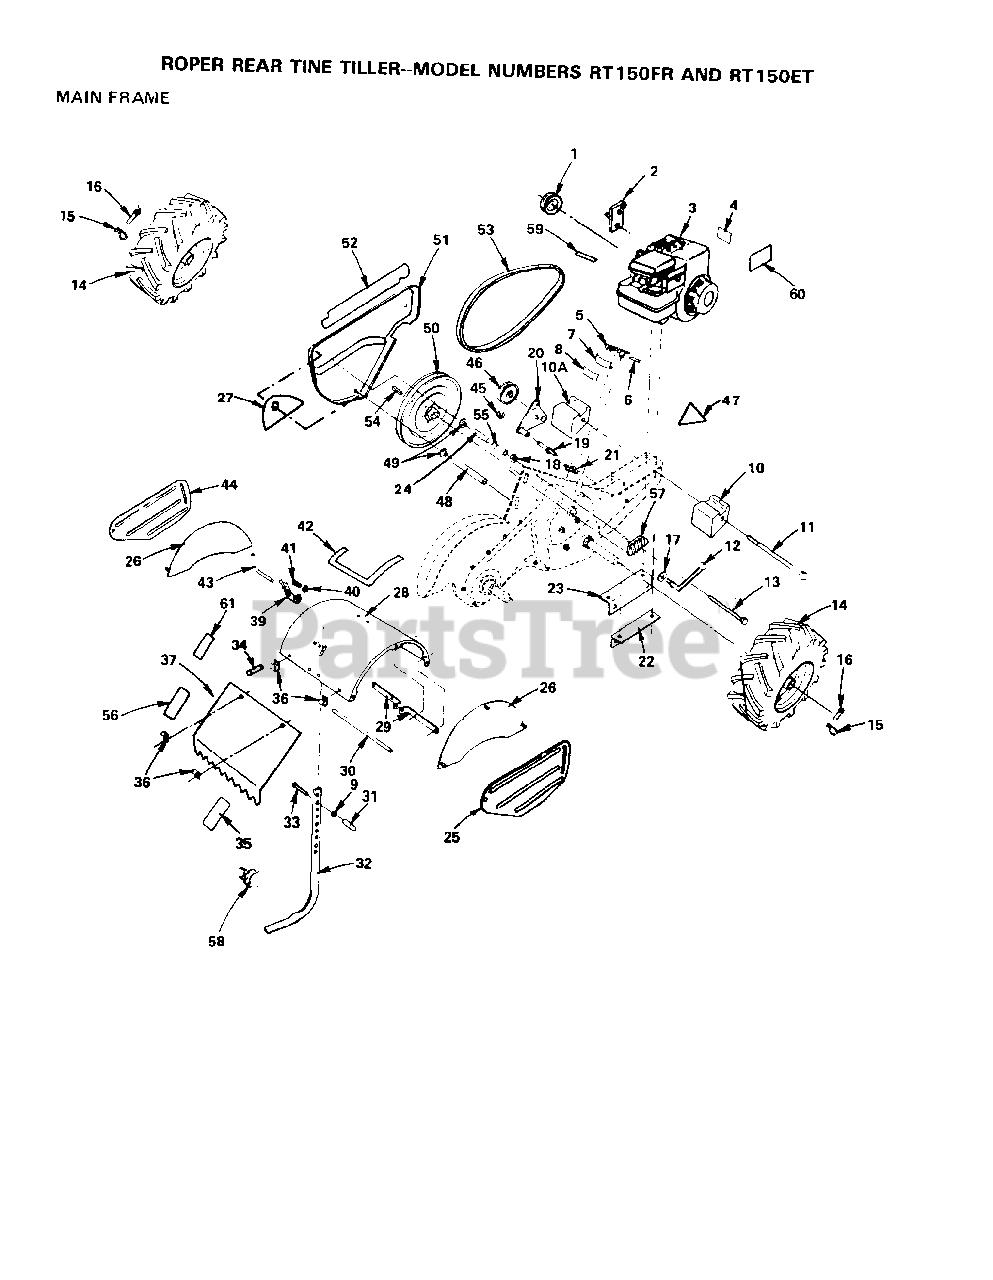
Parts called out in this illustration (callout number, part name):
2	BRACKET ASSY CRT
5	LEVER ASM CRT
7	PANEL TI
8	DECAL CRT
9	NUT.HEX.3/8-16UNC
10	COUNTERWEIGHT CRT
10A	COUNTERWEIGHT CRT
11	BOLT CRT
12	LEVER LOCK CRT
13	BOLT-HEX TI
15	RETAINER M
17	WASHER CRT
18	NUT.HEX.5/16-18
19	SHIFT ARM CRT
21	CONDIUT CLIP T
22	BRACKET RH CRT
23	BRACKET LH CRT
24	SPACER CRT
26	SHIELD CRT
31	GRIP CRT
33	BOLT
34	VINYL CAP TI
36	HINGE CRT
38	DECAL TI
39	LATCH BRACKET TI
40	KLIP RING TI
41	SPRING TI
42	DECAL - TINE SHIELD
43	STAKE PIN TI
44	SHIELD.SD.OUT.LH
45	KLIP RING
46	PULLEY-IDLER TI
47	DECAL - OPEI
49	WASHER
50	"SHEAVE 10"" CRT"
54	KEY T
55	SPACER CRT
56	DECAL - DEPTH ADJUSTMENT
57	LOCK - HANDLE
58	SPRING CRT
61	PAD IDLER TI
